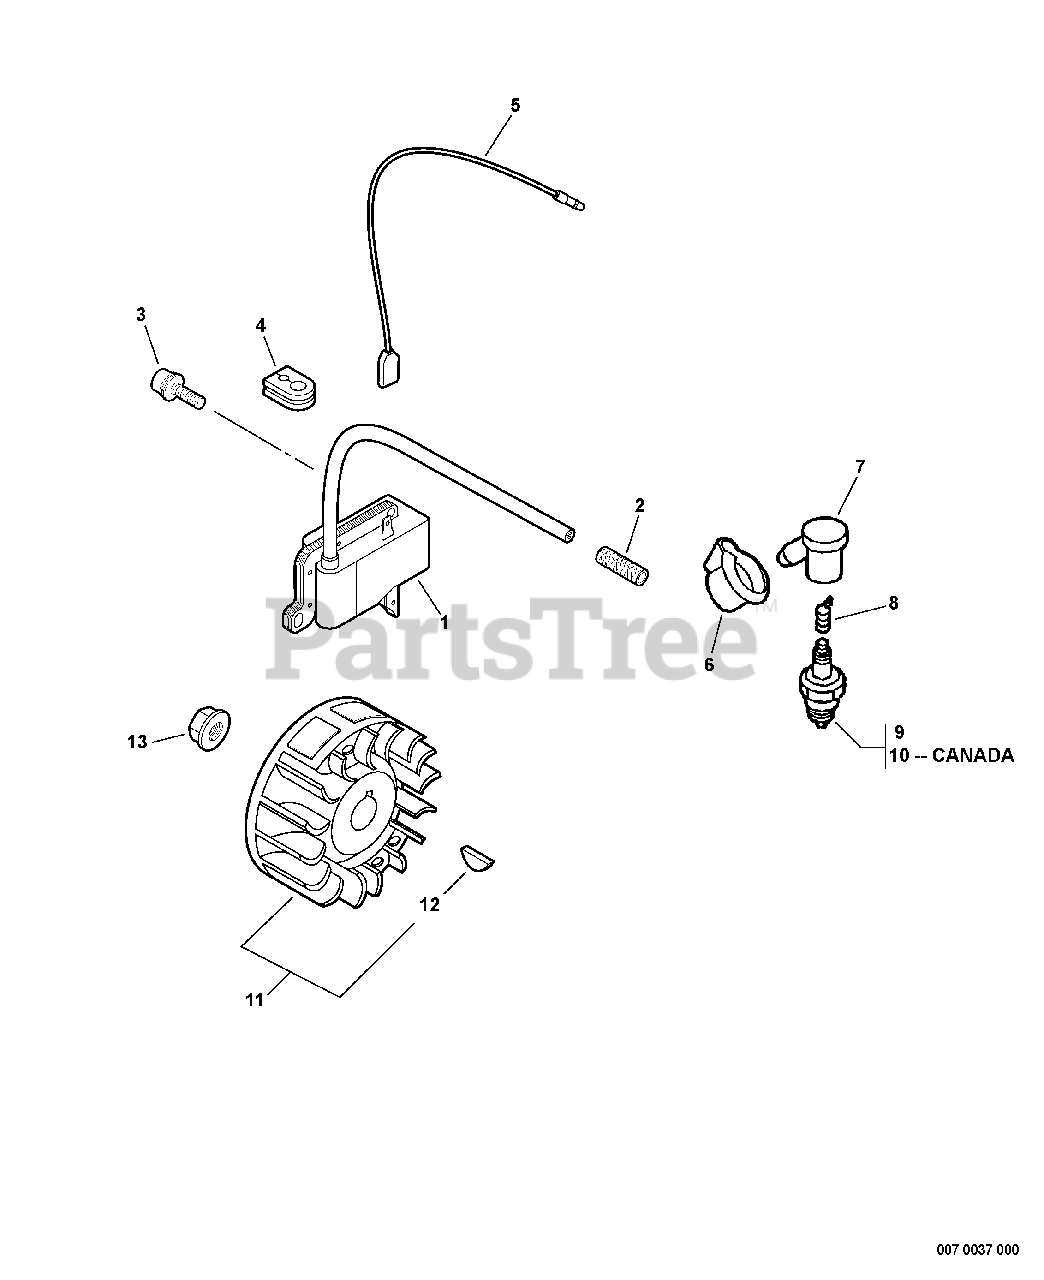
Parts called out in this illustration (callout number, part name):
1	COIL, IGNITION
2	TUBE, INSULATOR 7×8.6×55
3	BOLT 5×20
5	LEAD 170 MM
6	COVER, DUST
7	CAP, SPARK PLUG
8	TERMINAL, SPARK PLUG
9	SPARK PLUG - BPM7A
10	SPARK PLUG - RCJ6Y
11	FLYWHEEL KIT
12	KEY, WOODRUFF 3×14
13	NUT, FLANGE 10×1.25
